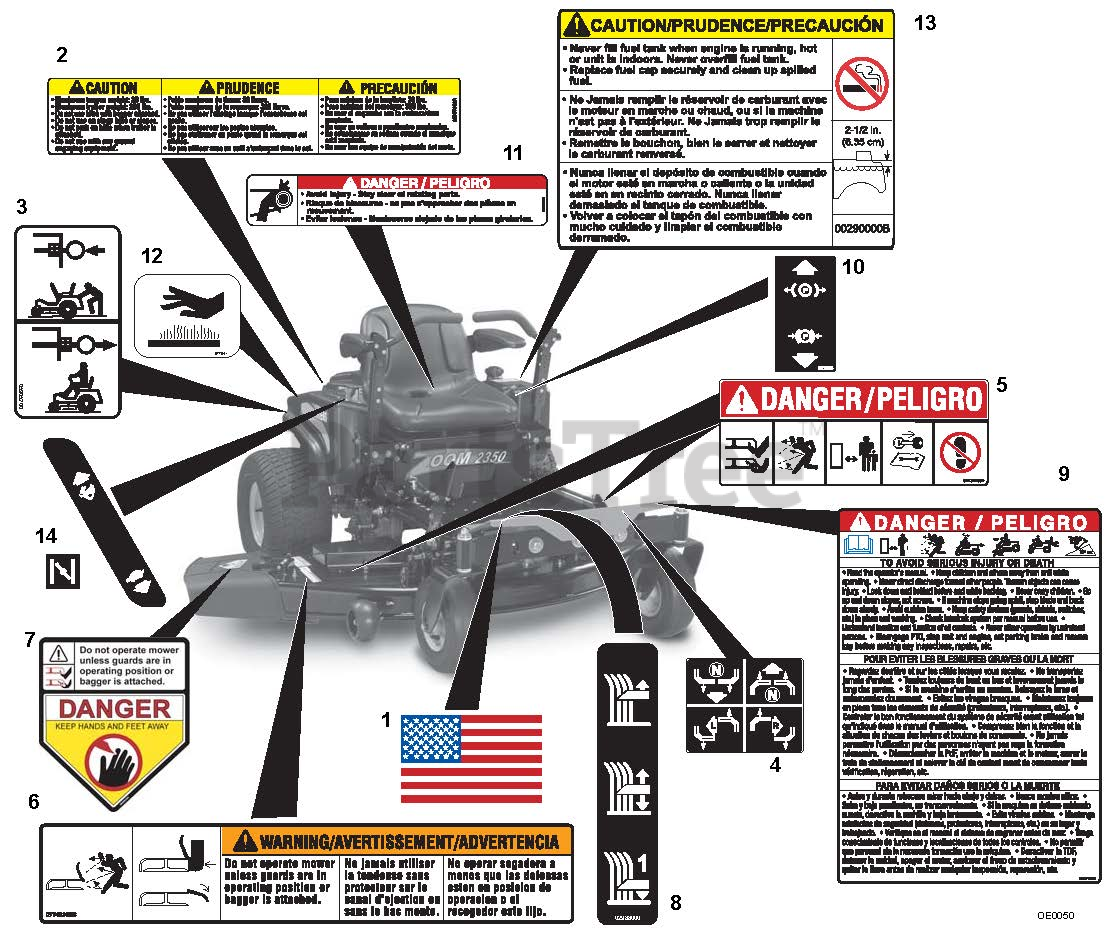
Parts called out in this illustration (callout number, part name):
1	DECAL, AMERICAN FLAG
2	DECAL, TRAILER HITCH
3	DECAL, TRANSMISSION DISCONNECT
4	DECAL, INSTRUCTIONAL-STEERING
5	DECAL, MOWER PAN DANGER
6	DECAL, WARNING
7	DECAL, CPSC DANGER
8	DECAL,CUT HEIGHT
9	DECAL, DANGER BILINGUAL
10	DECAL, PARKING BRAKE LEVER
11	DECAL- DANGER
12	DECAL, HOT SURFACE
13	DECAL,FUEL WARNING
14	DECAL, SPEED CONTROL
